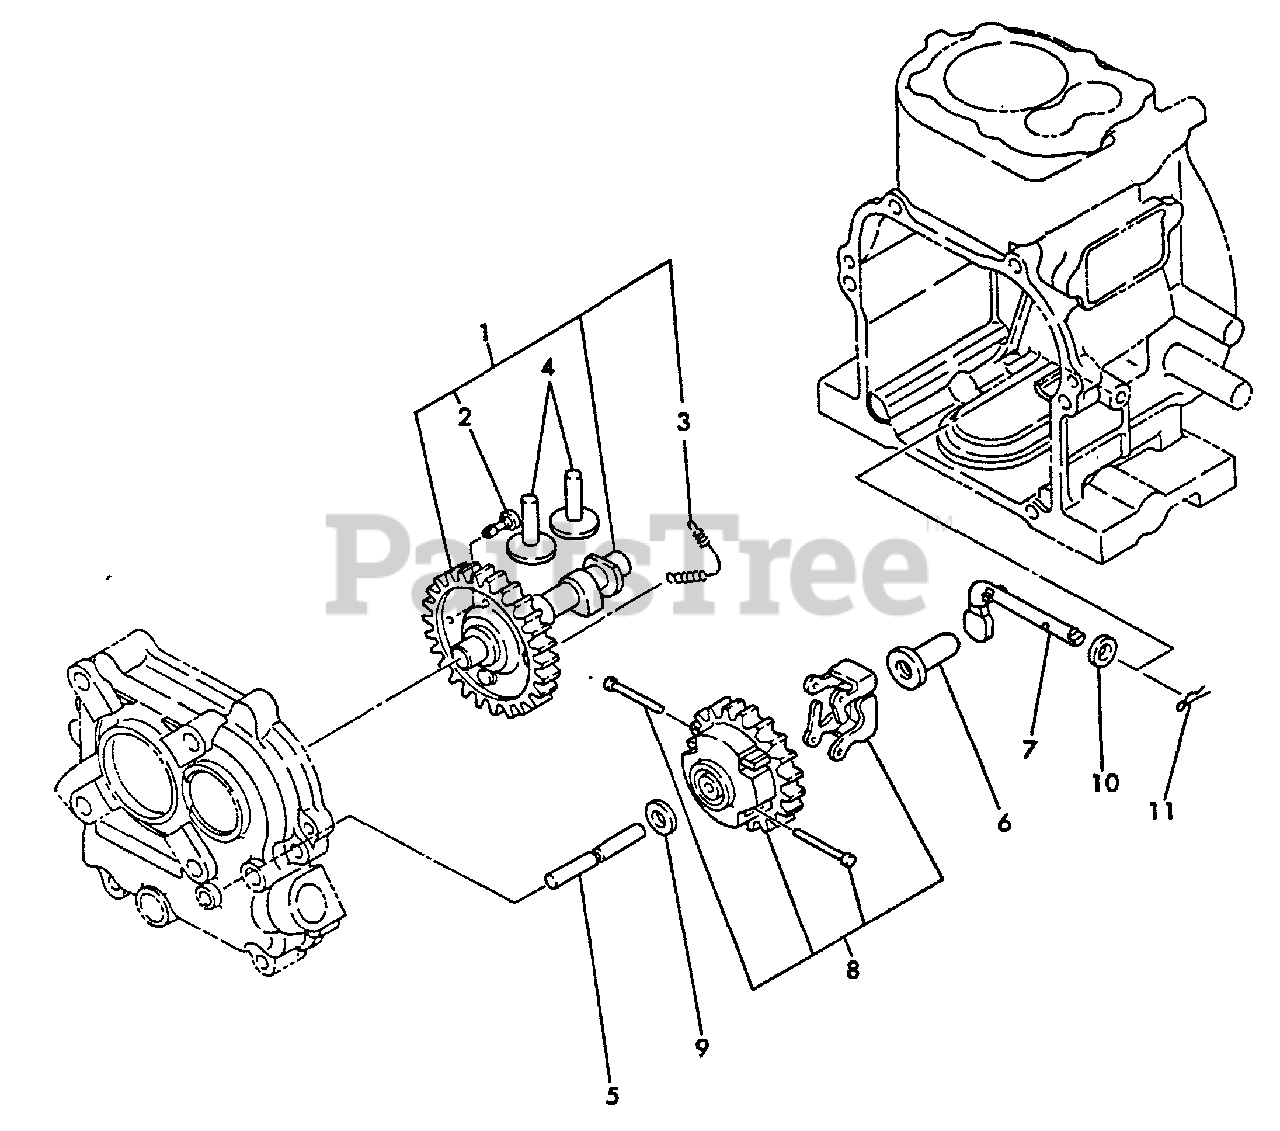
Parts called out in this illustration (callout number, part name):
1	CAMSHAFT ASSY
2	PIN, DECOMP.
3	SPRING
4	TAPPET
5	SHAFT, GOVERNOR
6	SPINDLE, GOVERNOR
7	SHAFT, GOV. LEVER
8	GOVERNOR GEAR ASSY
9	WASHER
10	WASHER - 6
11	PIN - 6 -- SNAP
